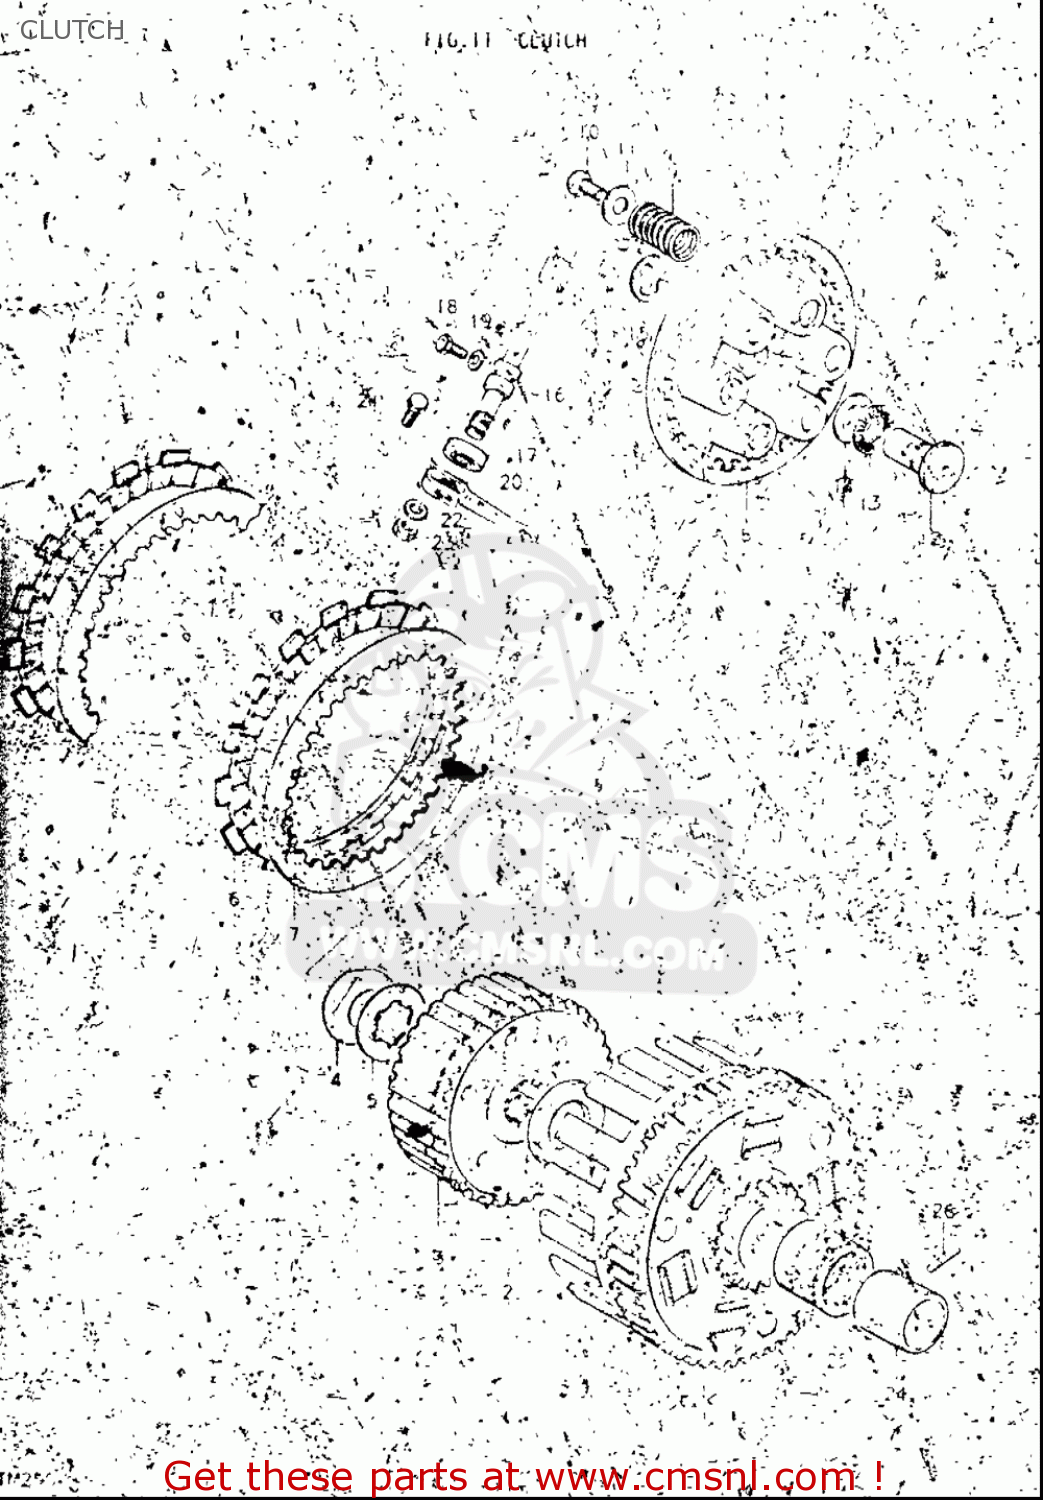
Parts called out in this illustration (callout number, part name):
2	WASHER(20X44X3)
4	NUT
5	WASHER,LOCK
6	PLATE,CLUTCH DRIVE(T:3.5) (NAS)
7	PLATE,CLUTCH DRIVEN(T:2.0) (NAS)
8	DISC,CLUTCH PRESSURE
9	SPRING
10	BOLT
11	WASHER(6.5X20X1.6)
12	RACK,CLUTCH RELEASE
13	BEARING(15X28X2)
14	WASHER(15.5X28X1)
15	E RING
16	PINION,CLUTCH RELEASE
17	SEAL,OIL (12X22X9)
18	BOLT(6X12)
19	WASHER
20	ARM,CLUTCH RELEASE
21	BOLT
22	WASHER
23	NUT
24	SPACER
25	BEARING
